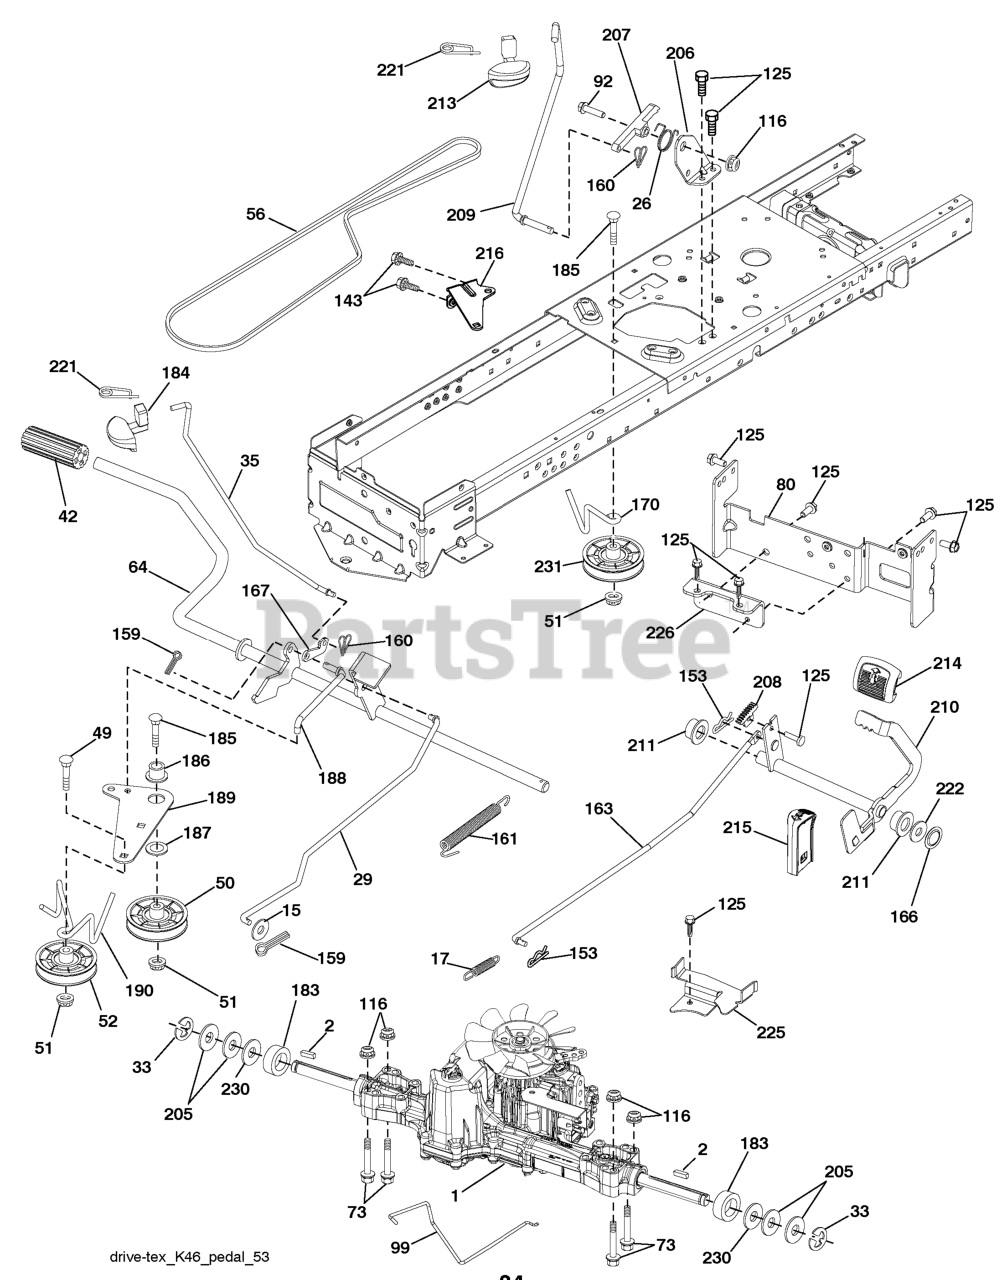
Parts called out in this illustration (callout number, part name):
1	Transaxle, TUFFTORQ K46 BT (See Transaxle breakdown)
2	SQUARE KEY
15	WASHER
17	SPRING.BRAKE.K46.GREEN
26	SPRING.RETURN.CRUISE
29	ROD.BRAKE.K46
35	ROD.BRAKE.PARKING.GT.H
42	PEDAL COVER T
50	IDLER.FLAT.910.OFFSET
51	NUT LOCK FLG 3/8-16 UNC
52	IDLER.V-GROOVE.910.OFFSET
56	V-BELT.MOWER.92.40.42/K46
64	SHAFT.ASM.PEDAL.BRK.CNTR
73	BOLT HEX 5/16-18 GR 5
80	STRAP TORQUE
92	BOLT
99	ROD.SPRING.BYPASS.K46.LT.Z
116	NUT LOCK HEX FLANGE 5/16-18
125	SCREW
143	Screw 5/16-18 x 1/2
153	RETAINER M
159	COTTER PIN
160	RETAINER CLIP
161	SPRING, RETURN LT
163	ROD.CONTROL.PEDAL.K46
166	NUT.PUSH.625
167	LATCH.BRAKE.SPRING
170	KEEPER.CENTER SPAN.1.688
171	BOLT
183	SPACER AXLE
184	HANDLE.PARKG.BRK.HUSQ X667
186	SPACER.RETAINER
187	WASHER 12/32X2X10GA
188	RP.LINK.CLUTCH.GROUND.DRIVE
189	BELLCRANK.GROUND.DRIVE.TEX.
190	KEEPER.BELLCRANK.DRIVE
206	BRKT.MOUNT.LATCH.CRUIS
207	LATCH.CONTROL.CRUISE
208	GEAR.SECTOR.CONTROL.CR
209	ROD.CONTROL.CRUISE.GT.
210	ROCKER.ASM.PEDAL.CONTR
211	BEARING.NYLON
213	KNOB.CONTROL.CRUSIE.HU
214	PEDAL.FORWARD.PAD.TEX
215	PEDAL.REVERSE.TEX.GT.4
216	BRACKET.PULLEY.IDLER.W/TEX
221	RETAINER.SPRING.CLIP.H
222	WASHER 21/32 X 1-1/4 X 10 GA.
225	KEEPER.BELT.TRANSAXLE.K46
226	BRACKET.MOUNT.TORQUE.K46.TLT
230	WASHER.HARDENED
231	IDLER.V-GROOVE.1.688.OFFSET
